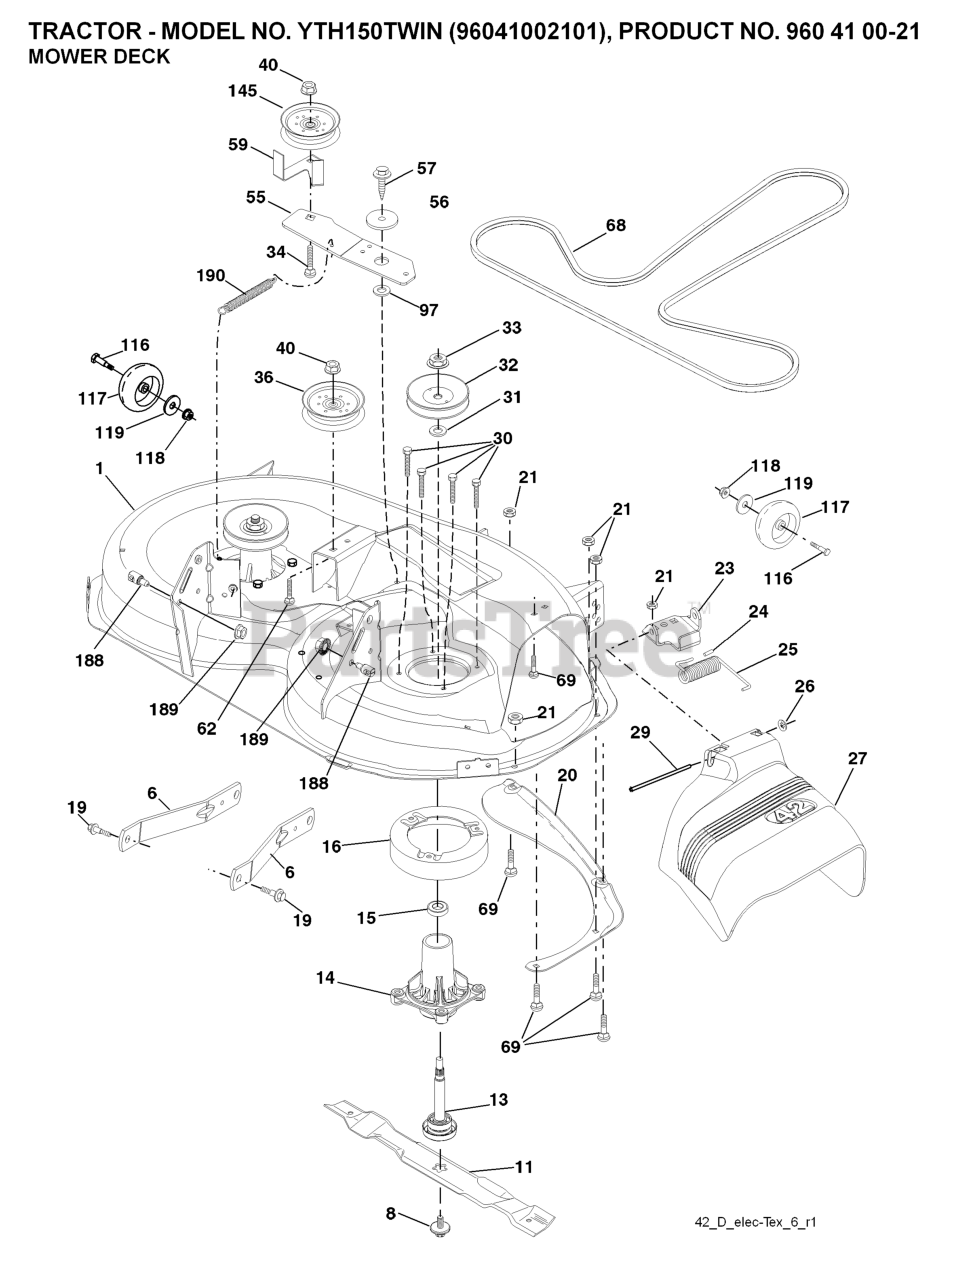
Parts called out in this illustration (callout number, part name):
1	DECK.WELDMENT.42"
6	ARM.SUSPENSION.MOWER.R
8	BOLT.WASHER.ASM.7/16-2
11	42" HI-LIFT BLADE
13	SHAFT.ASM.MDRL.N/GREASE.38
14	RP.HOUSING.MANDREL.4PT.
16	STRIPPER.MANDREL.ROUND.BLACK
19	BOLT.SHOULDER
20	BAFFLE.VORTEX
21	LOCKNUT
23	BRKT.DEFLECTOR.38"2005+
24	CAP-SLEEVE LT
25	SPRING.TORSION.DEFLECT
26	NUT PUSH M
27	SHIELD.DEFLECTOR.MOWER.42"BLAC
29	ROD.HINGE
30	SCREW, WASHER HEAD
31	WASHER.SPACER.MANDREL
32	PULLEY/MANDREL
33	NUT.FLANGE.LOCK.TOP
34	BOLT.3/8-16X1.50
36	PULLEY.IDLER.2006
40	NUT LOCK FLG 3/8-16 UNC
56	SPACER.RETAINER
57	SCREW 3/8-16X1
59	GUARD, BELT
68	BELT V SECONDARY
69	BOLT
116	BOLT M
117	WHEEL.GAGE.HALF.SPOKED
118	LOCKNUT
119	WASHER.5/16.FLAT.STE.STD.
145	PULLEY.IDLER.48"PRIMARY
188	STUD.FASTNER.W/ANTI-ROTATE
189	NUT LOCK HEX FLANGE 5/16-18
190	SPRING.MOWER.DRIVE.ELECTRIC
